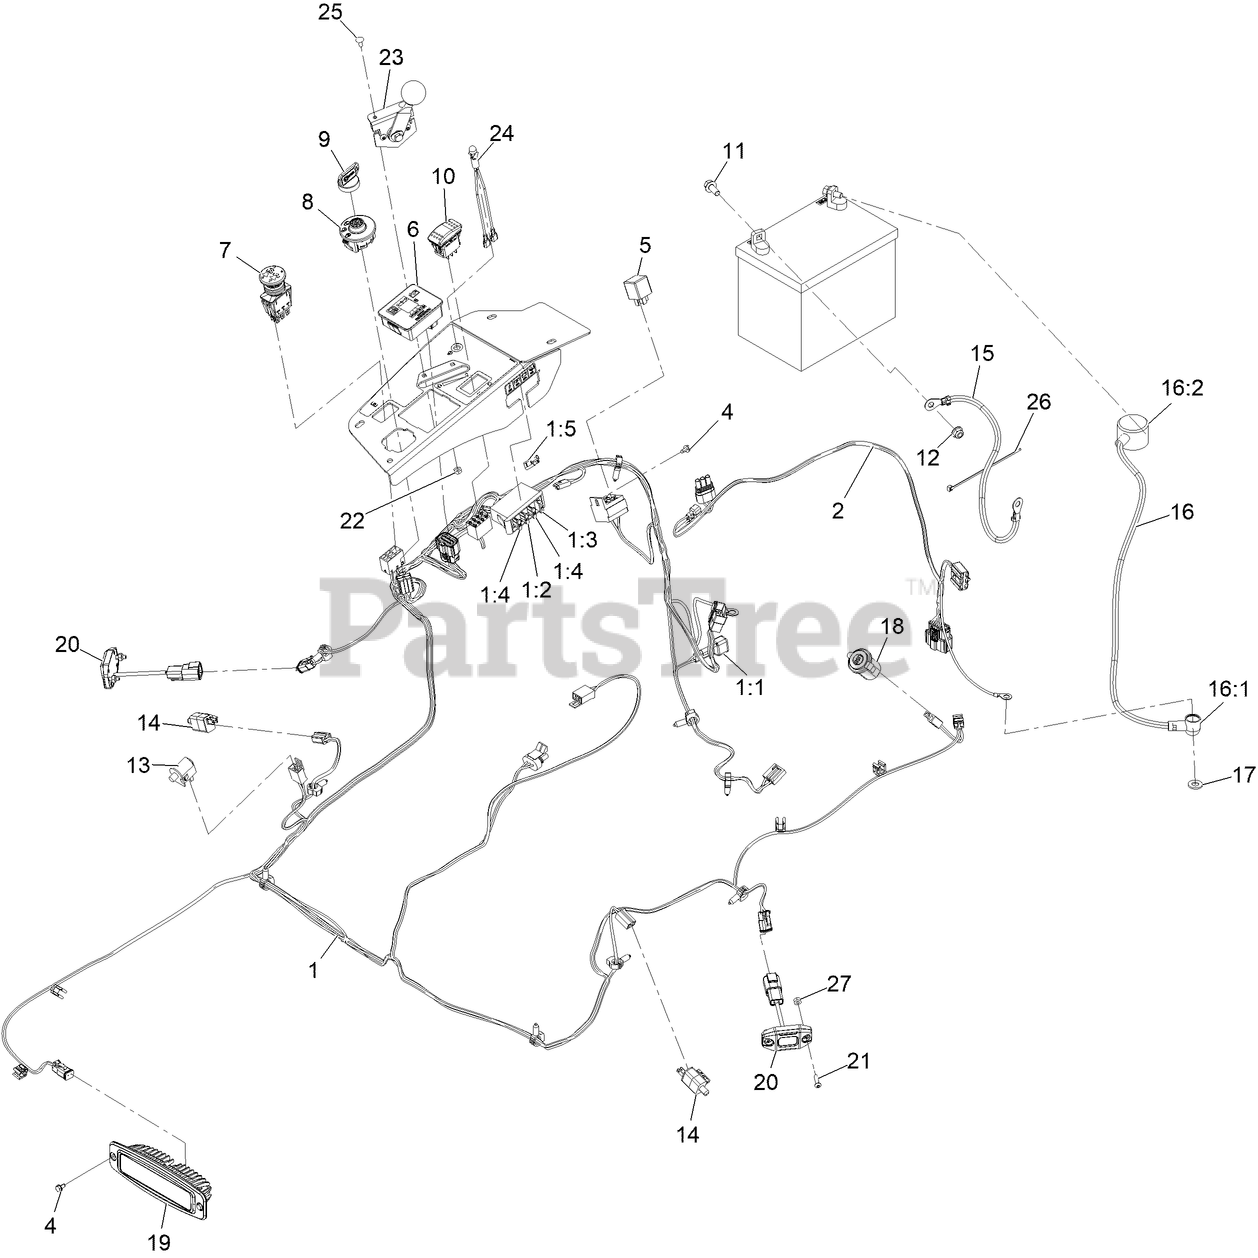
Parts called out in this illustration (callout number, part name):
1	HARNESS-MAIN LRX CARB
1:2	FUSE-BLADE, 10 AMP
1:3	FUSE-BLADE, 15 AMP
1:4	FUSE-BLADE, 25 AMP
1:5	CAP-PLUG
2	Harness-Adapter EFI, Etc
4	SCREW-HWH
6	FUEL/HOUR METER ASM
7	SWITCH, PTO 10A
8	SWITCH-IGNITION
9	KEY-IGNITION
11	SCREW-HHF
12	NUT-HF, NI
13	SWITCH-BAIL
15	Cable-Battery, Black
16	POSITIVE BATTERY CABLE AS
16:1	INSULATOR-SOLENOID
16:2	INSULATOR-BATTERY
17	WASHER-FLAT
18	PORT-POWER, USB
19	MOUNT-FLUSH, LIGHT
20	LIGHT-ROCK
21	Screw-HSBH
22	NUT-LOCK, NI
23	THROTTLE CONTROLLER-ETC
24	INDICATOR-LED, RED
25	BOLT-CARR
26	TIE-CABLE
27	Nut-Speed
